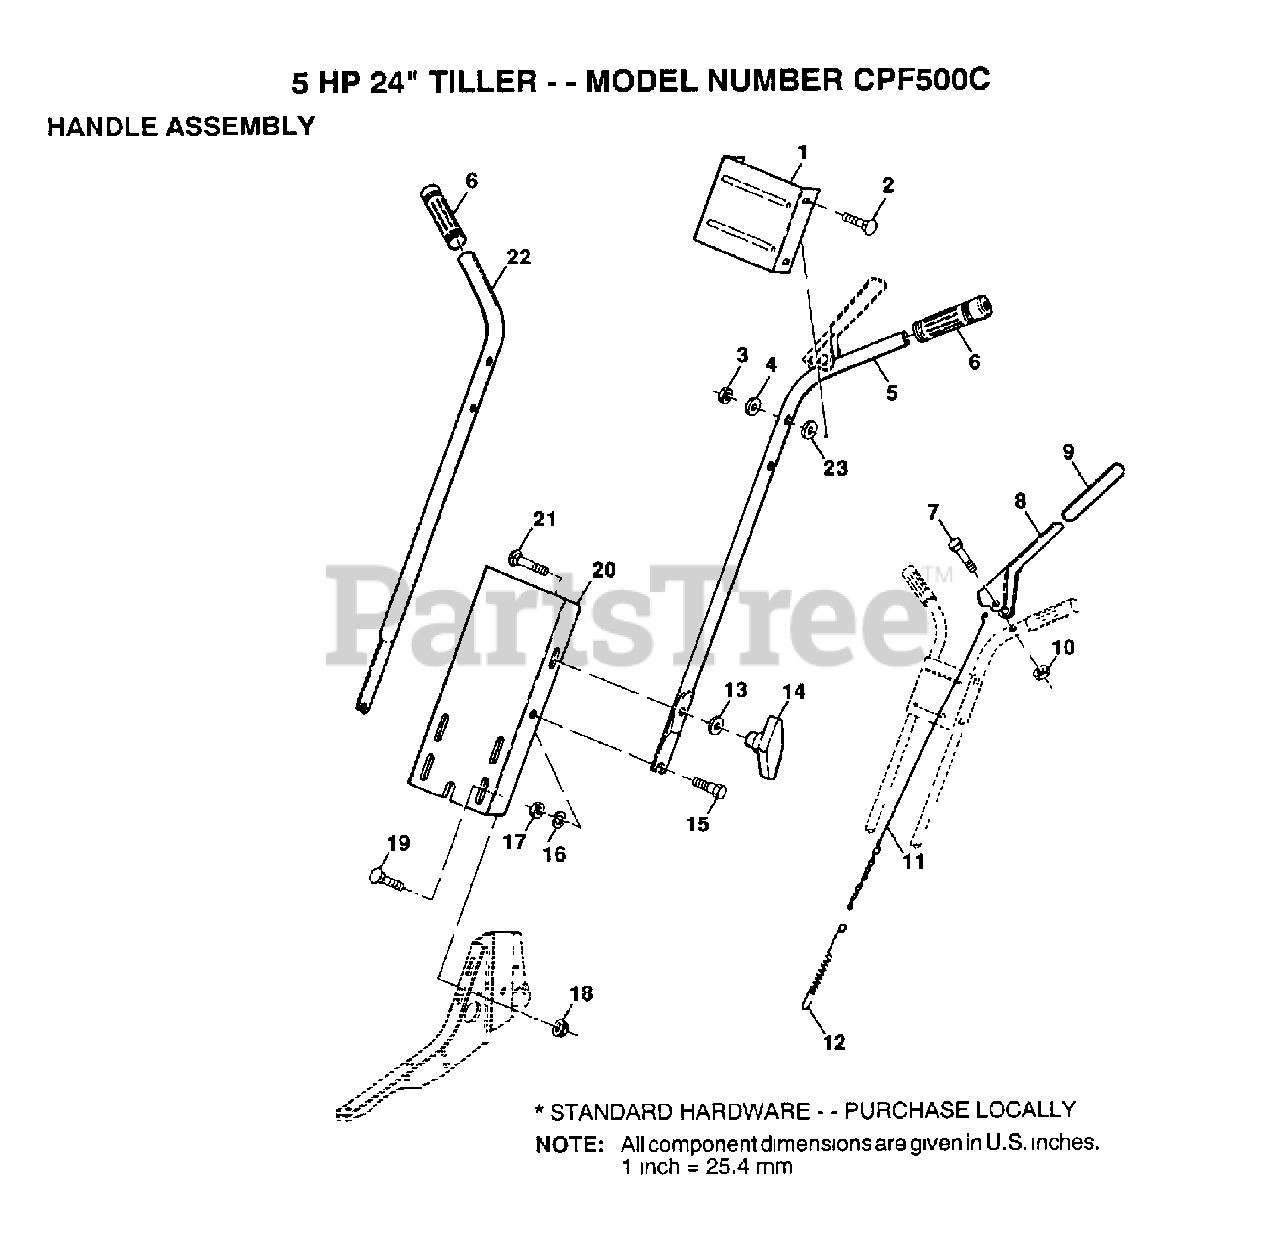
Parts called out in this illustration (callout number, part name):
1	BRKT. HANDLE
2	BOLT
4	WASHER
7	BOLT.HEX.5/16-1.5
9	GRIP T
12	SPRING EXT TI
13	WASHER
14	KNOB HANDLE
16	LOCKWASHER
17	NUT.HEX.5/16-18
18	NUT
19	BOLT
20	"PANEL, HANDLE"
21	BOLT
23	WASHER
